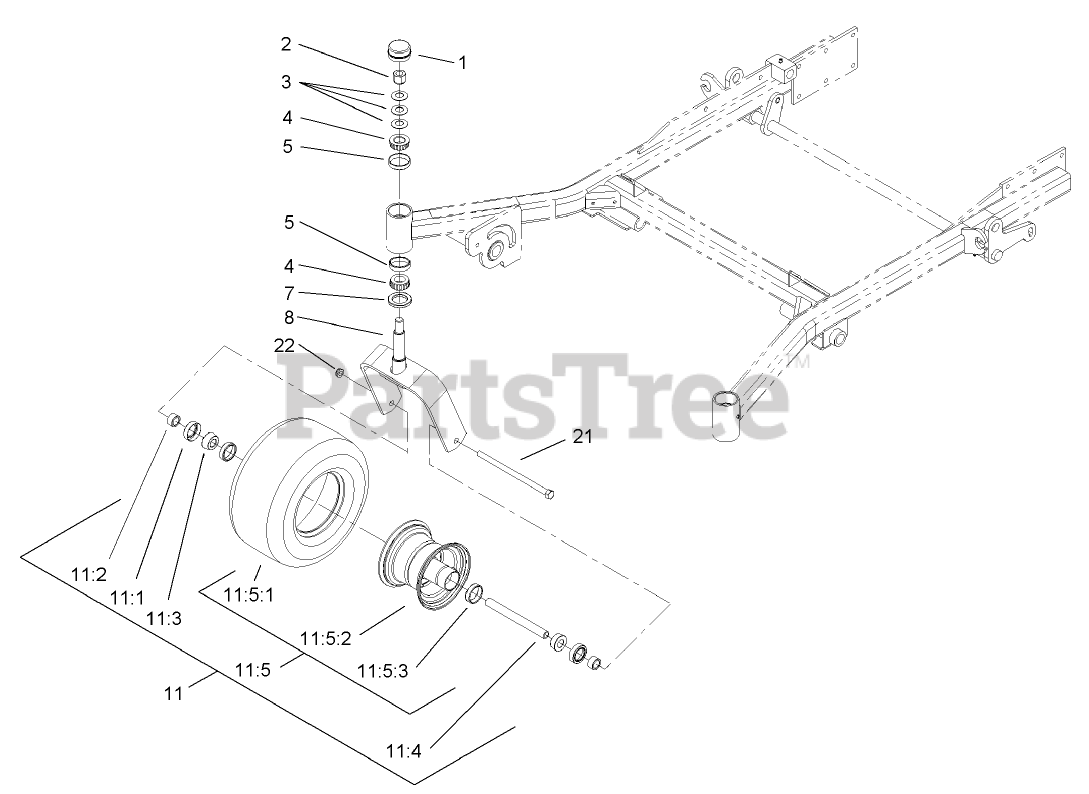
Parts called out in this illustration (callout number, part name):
1	CAP-GREASE
2	NUT-LOCK, NI
3	WASHER-BELLVILLE
4	BEARING-CONE, TAPERED
5	BEARING-CUP, TAPERED
7	SEAL-GREASE
8	CASTER-FORK
11	CASTER WHEEL ASM
11:1	SEAL-BEARING
11:2	SPACER-BEARING
11:3	BEARING-CONE, TAPER
11:4	SPACER-CASTER, FRONT
11:5	WHEEL AND TIRE ASM
11:5:3	BEARING-CUP
21	Screw-HH
22	NUT-LOCK, NI
